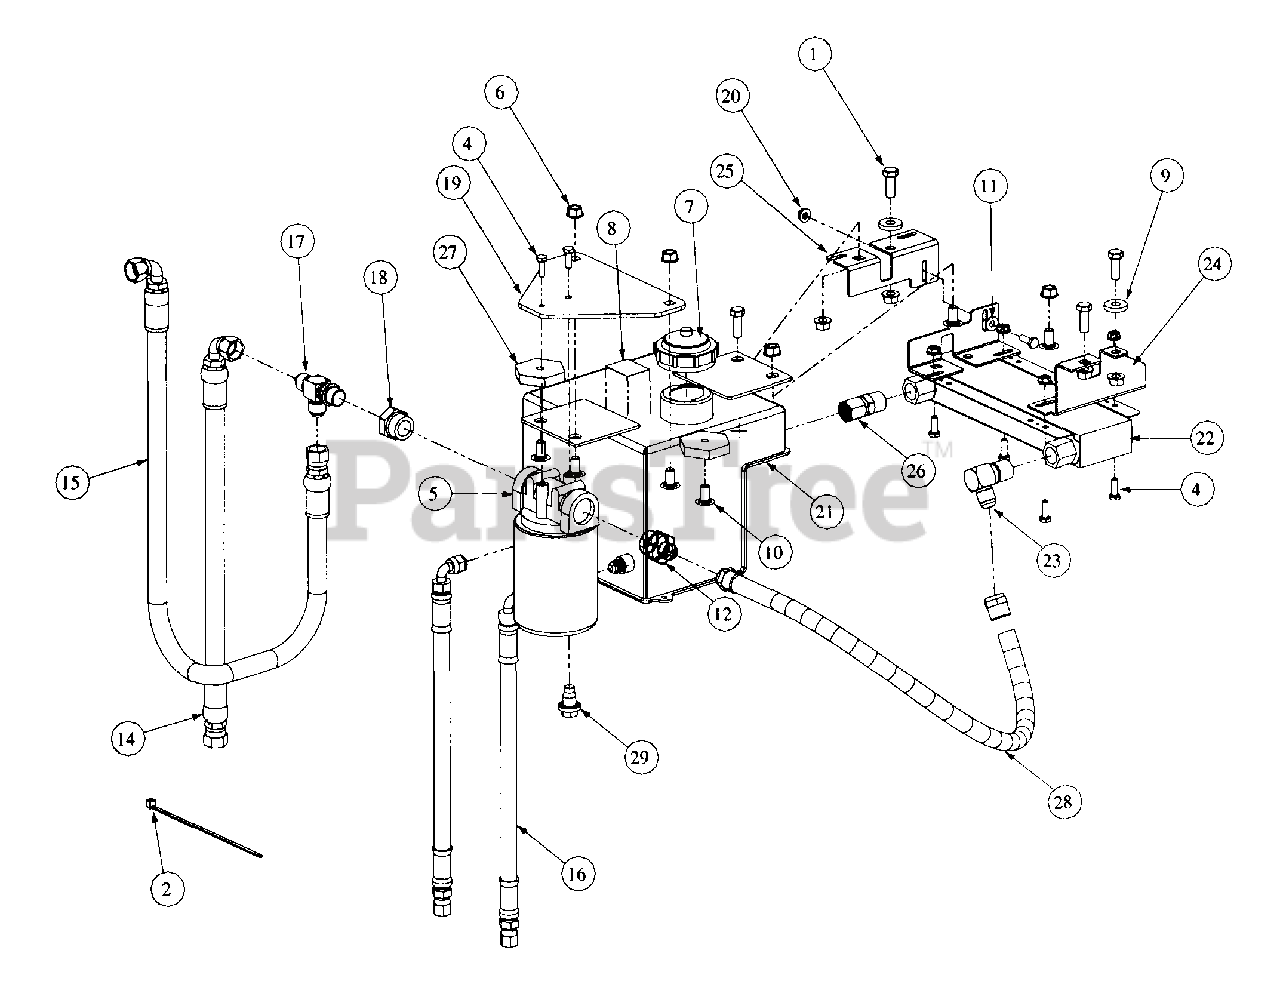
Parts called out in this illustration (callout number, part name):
1	Hex Cap Screw, 3/8-16, 1
2	Cable Tie, 3/16 x .05 x 7.4
4	Hex Cap Screw, 1/4-20, .75
5	Filter Head, 3/4
6	Hex Nut Flange Lock, 3/8-16
7	Cap, Hydro Oil Tank
8	Decal Oil Only, 20W50
9	Idler Washer
10	Carriage Bolt, 3/8-16 x .75 LG
11	Flatwasher, 1/4 x .630 x .0515
12	Straight Connector, 1/2 x 3/4
14	Hydraulic Hose Filter, Right
15	Hydraulic Hose Filter, Left
16	Hydraulic Hose, Pump to Tank
17	Tee Fitting, 1/2 x 1/2 x 3/4
18	Adapter, 1/2 x 3/4
19	Mount Plate Oil Filter
20	Hexflange Lock Nut, 1/4-20
21	Hydraulic Tank Assembly
22	Heat Exchange, 1.5 x 11 x 2.77 LG
23	Elbow Fitting, 1/2 NTPF x 1/2
24	Mount Bracket, RH Heat Exchange
25	Mount Bracket, LH Heat Exchange
26	Swivel Connector Fitting, 1/2 NPTF x 1/2
27	Spacer, 2.000 Hex x .41 LG
28	Hose Assembly, Oil Cooler to Filter
29	Oil Pan Drain Plug, w/Seal
